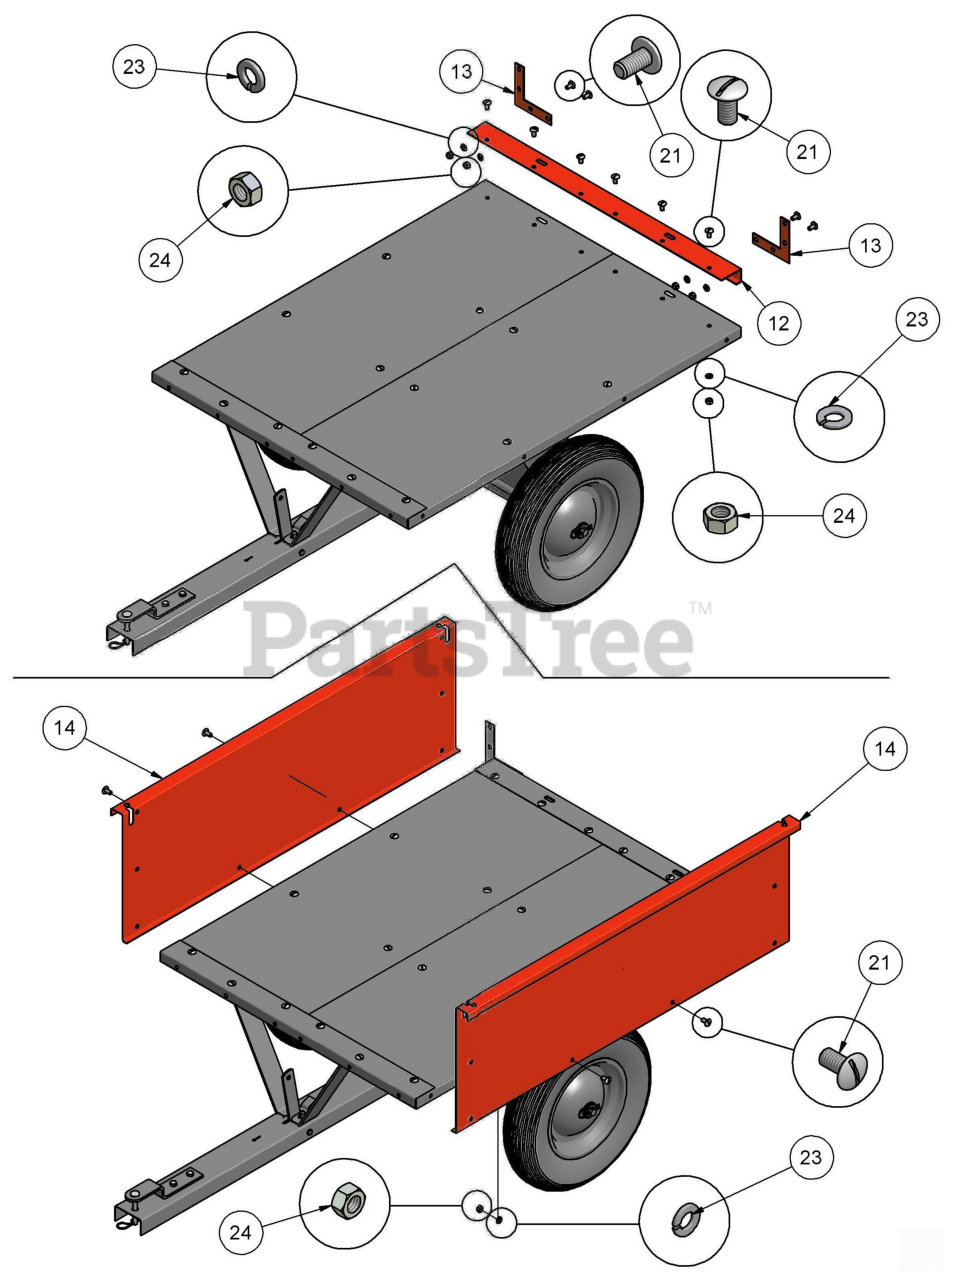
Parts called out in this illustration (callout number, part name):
12	REAR CROSS BRACE
13	REAR CORNER BRACKET
14	SIDE PANEL
21	M8 X 16 TRUSS HEAD BOLT
23	8MM LOCK WASHER
24	8MM HEX NUT
